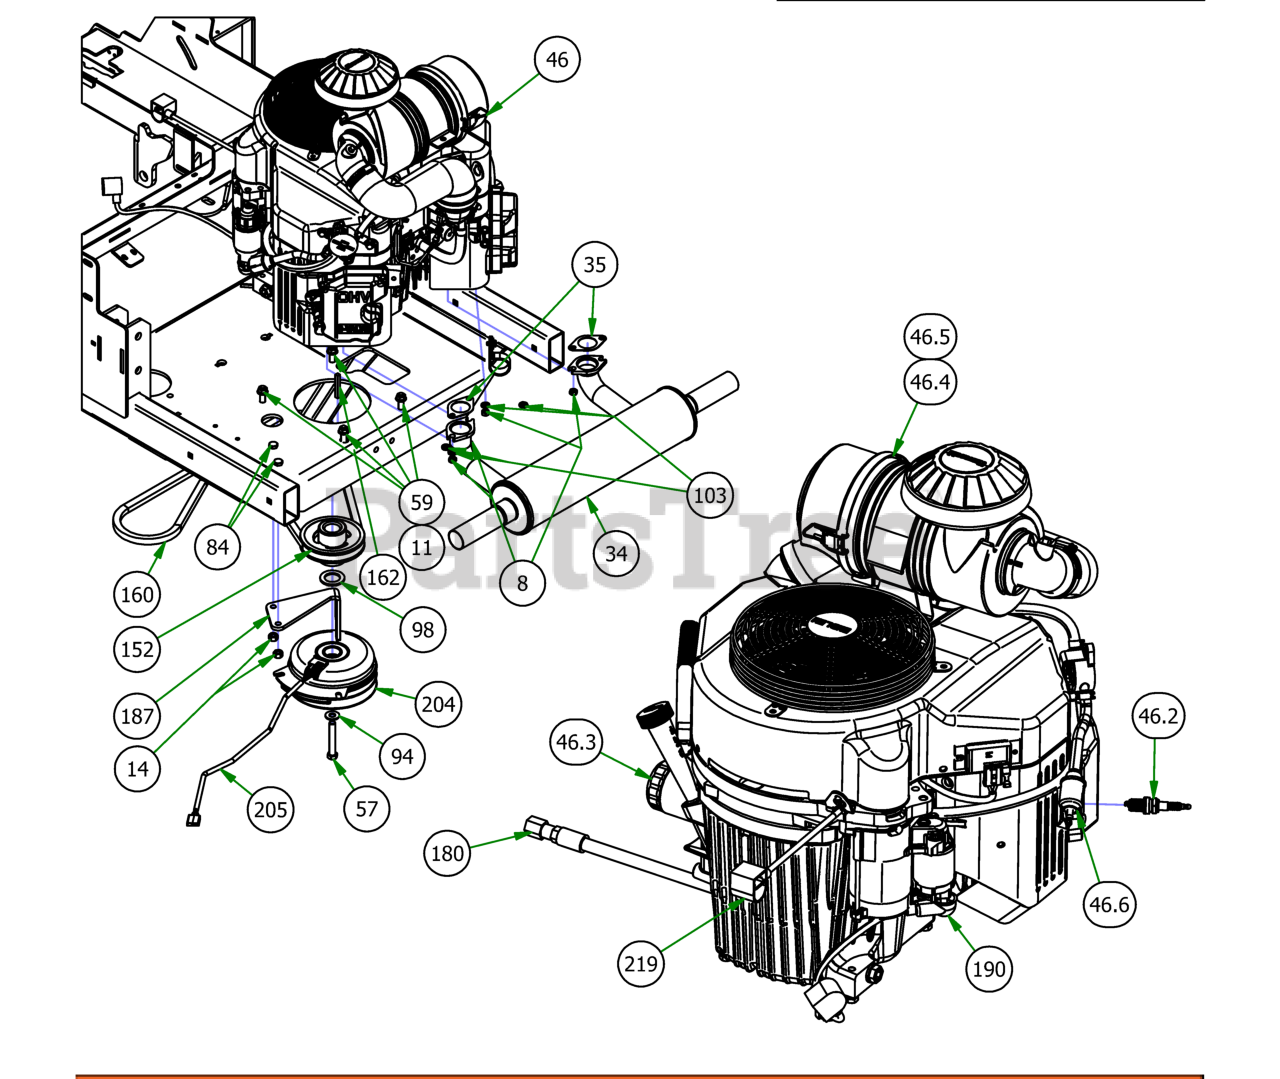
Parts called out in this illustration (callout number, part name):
8	M8-1.25 Zinc Nut
11	3/8-16 HEX SERRATED FLANGE NUT HARD/ZINC
14	3/8" Hex Nut
34	Muffler for Kawasaki FX1000
35	Exhaust Gasket
46	Kawasaki FX1000 Engine
46.2	Spark Plug - Kawasaki
46.3	Oil Filter
46.4	Canister Air Filter- Inner
46.5	Canister Air Filter- Outer
46.6	Universal Inline Fuel Filter
49	M6-1.0 X 12MM DIN 933 HEX TAP BOLT (CL 8.8) ZINC
57	7/16-20 x 2 3/4 Hex C/S GR 8 Yellow Zinc
59	3/8 x 1 1/8 bolt
82	3/8 x 1 1/2 Bolt
84	3/8" x 1" Hex Bolt
94	3/8 FLAT WASHER USS (1" OD) ZINC
98	1 1/8" Flat Spacer
100	1/4 USS Flat Washer Zinc
103	5/16" Lock Washer
152	4 3/4 Motor Pulley
160	2019 Rogue Pump Belt 68"
162	1/4 x 2 Square key Stock
180	Kawasaki Oil Drain
187	PTO Engager Holder
190	24" Red Battery Cable
204	Clutch Assembly
205	Clutch Pigtail
206	2019 Veritical Suspension Frame
208	Diesel Hydraulic Hose Clamp
219	Starter Cable
221	Kawasaki Harness Adapter
